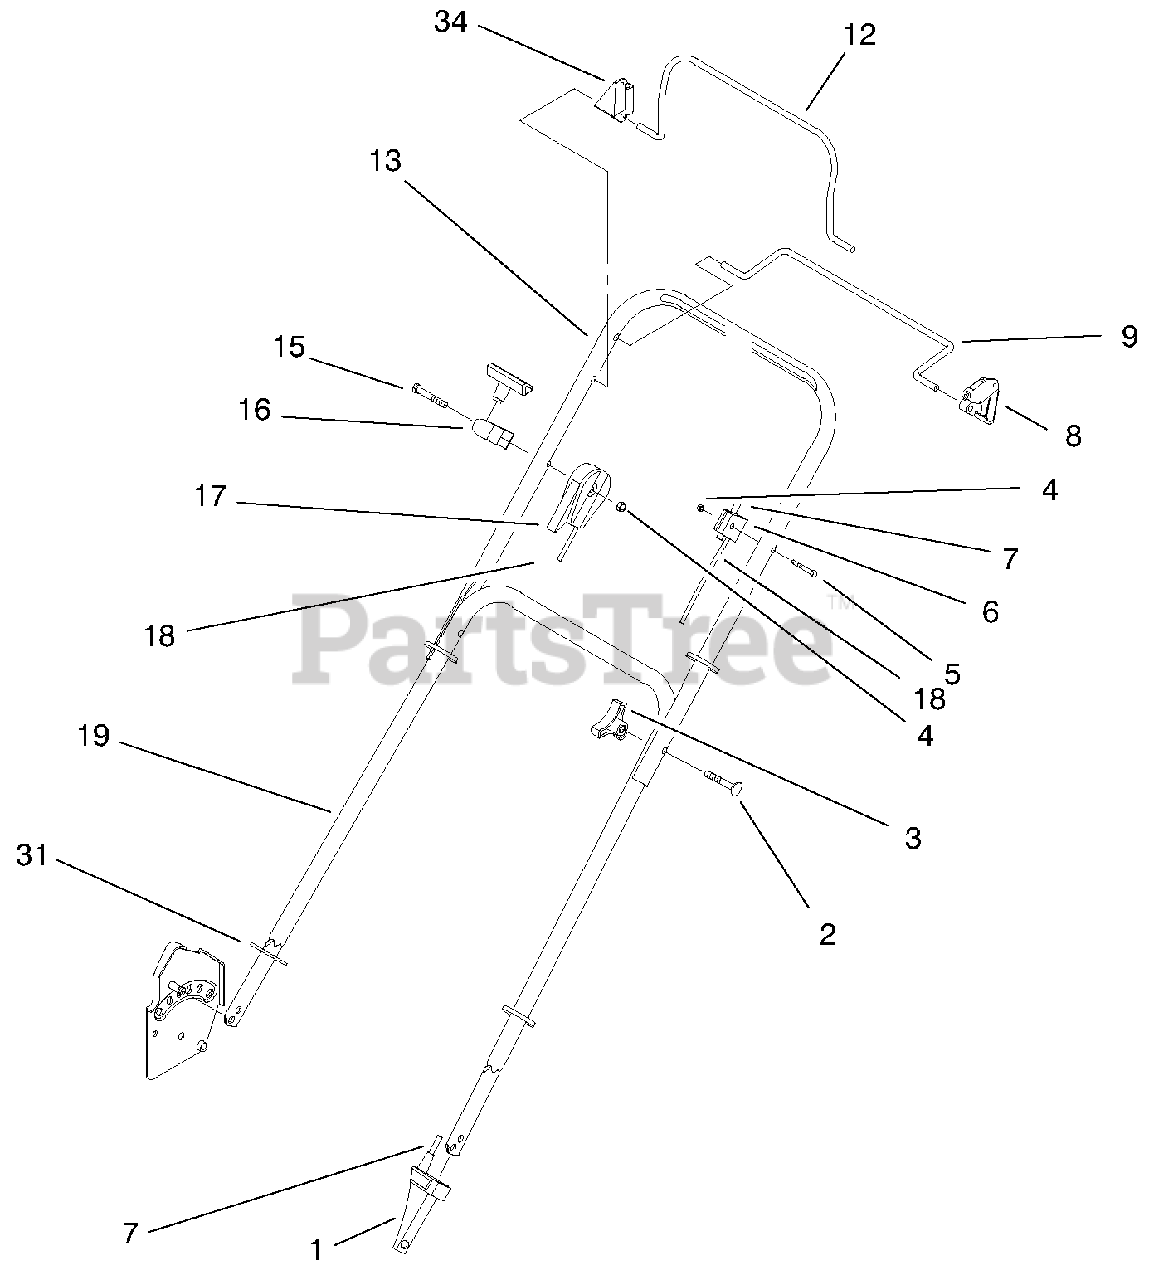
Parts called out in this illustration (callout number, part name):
1	Anchor-Cable
2	Screw-Handle
3	Knob
4	Nut-Lock
5	Screw-Handle
6	Anchor-Cable
7	Cable-Traction
8	Stop-Pivot
9	Bail-Sp Control
11	Card-Product Description
12	Bail-Flywheel Brake
13	Handle Section-Upper
16	Guide-Rope
17	Cable-Throttle
18	ASM-Brake Cable
19	Handle Section-Lower
31	Handle-Guard
34	Stop-Bail
35	Applique-Shroud
